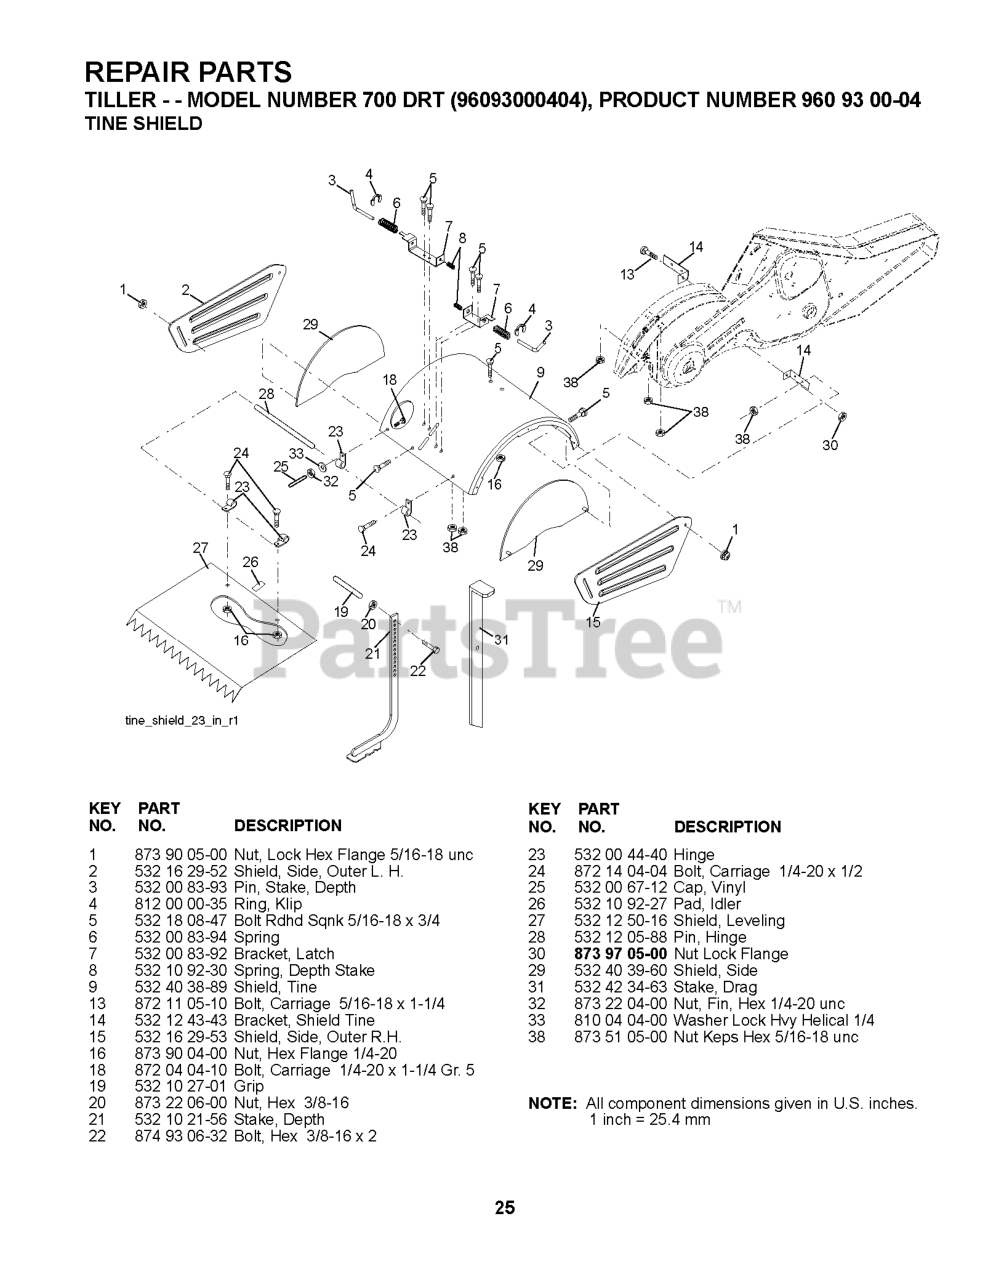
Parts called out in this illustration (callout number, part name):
1	NUT LOCK HEX FLANGE 5/16-18
2	SHIELD
3	STAKE PIN TI
4	RING, KLIP
5	BOLT, RDHD SQNK 5/16-18 X 3/4
7	BRACKET.LATCH.STAKE.3.20.BLACK
8	SPRING CRT
9	SHIELD.PNT.TINE.17"M
13	BOLT.CARRIAGE.5/16-18
14	BRACKET.TINE.SHIELD.TILLER
15	SIDE SHIELD RH
16	NUT T
20	NUT.HEX.3/8-16UNC
21	STAKE.DEPTH.16.CRT.BLACK
22	BOLT.375-16
26	PAD IDLER TI
27	SHIELD LEVELING
28	PIN.HINGE.TILLER
29	SHIELD.ASM.SIDE.ORANGE.(OLD)
30	LOCKNUT-FLANGE 5/16-18
31	RP.STAKE.DEPTH.DRAG.TILLR.GREY
32	NUT
33	LOCKWASHER
38	NUT
